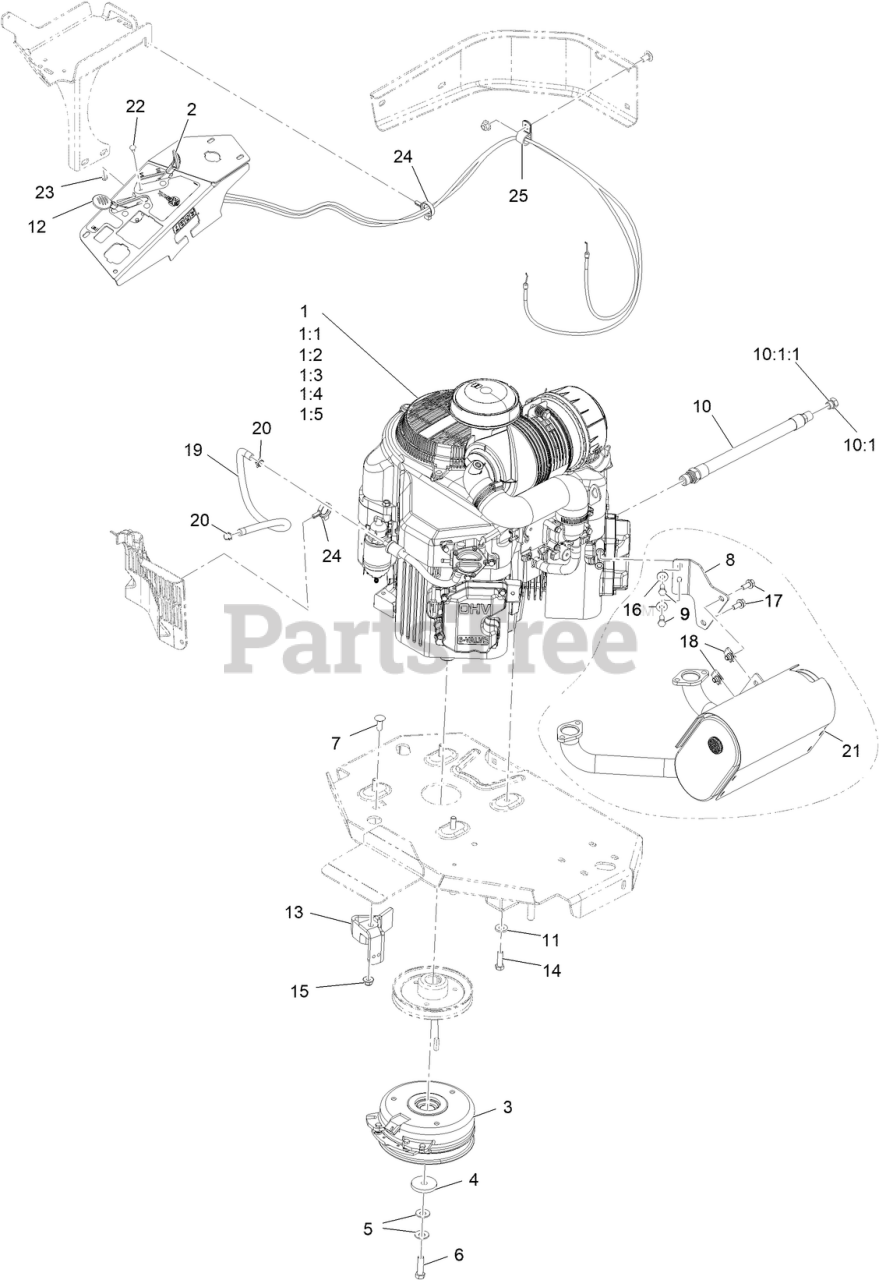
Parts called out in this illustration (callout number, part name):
1:1	FILTER-OIL KAW
1:2	ELEMENT-FILTER, AIR (OUTE
1:3	ELEMENT-FILTER, AIR (INNE
1:4	FILTER-FUEL
1:5	Spark Plug
2	CONTROL, CHOKE
3	CLUTCH KIT
4	WASHER-CLUTCH
5	WASHER-SPRING
6	SCREW-HH 7/16-20 X 1 1/2 W/LOCTITE
7	SCREW-CARR
8	BRACKET-MUFFLER
9	SCREW-HH
10	ENGINE OIL DRAIN HOSE ASM
10:1	PLUG-HH
10:1:1	O-RING
11	WASHER-BELLEVILLE
12	ASM,THROTTLE CABLE
13	CLUTCH-ANCHOR
14	SCREW-HH
15	NUT-HF, NI
16	WASHER-SPRING
17	SCREW-HHF
19	HOSE-FUEL
20	CLAMP-HOSE
21	MUFFLER
22	BOLT-CARR
23	NUT-LOCK, NI
24	CLAMP-HOSE
25	CLIP-LOOM
